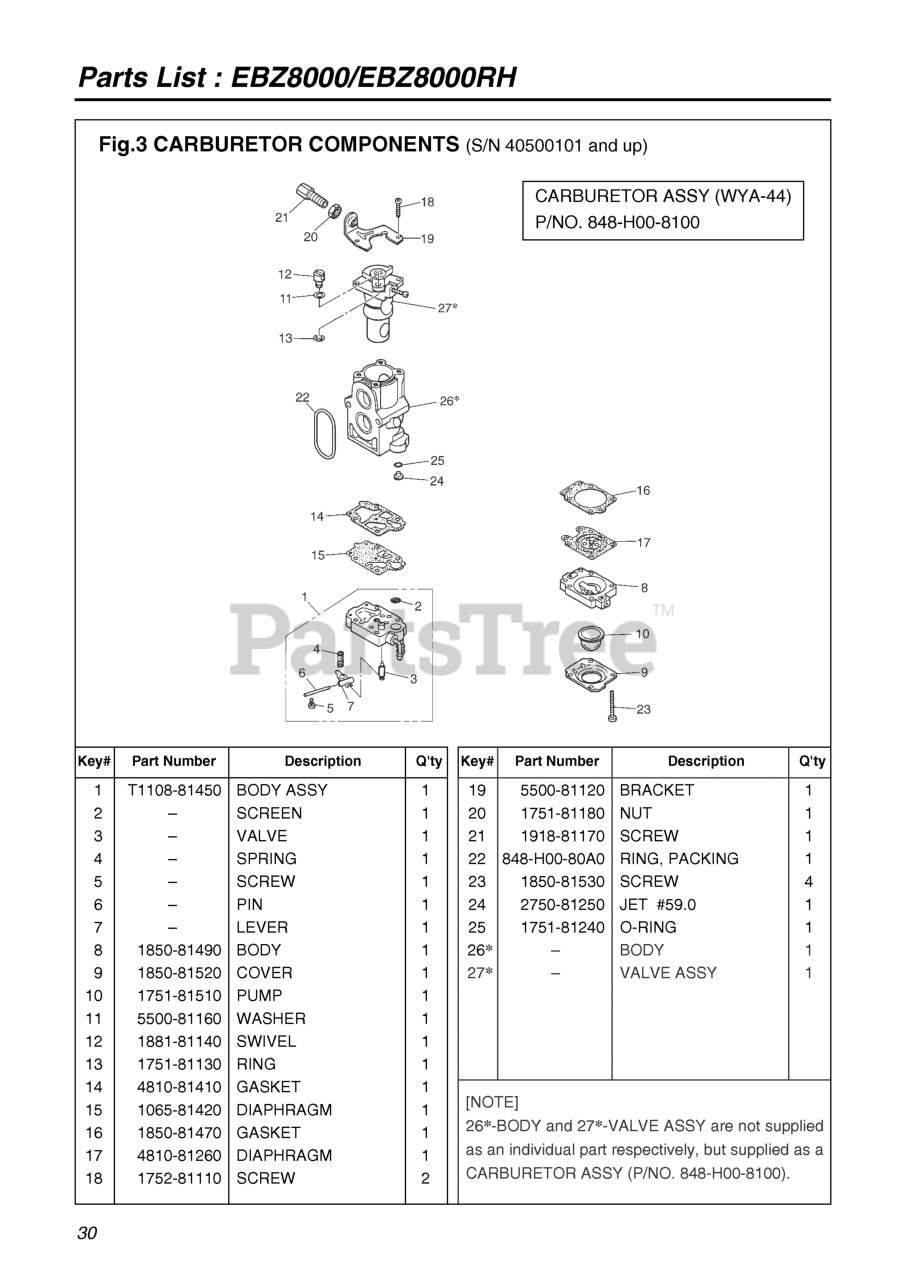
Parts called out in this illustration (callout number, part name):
1	BODY ASSY.
2	SCREEN
3	VALVE
4	SPRING
5	SCREW
6	PIN
7	LEVER
8	BODY, PURGE
9	COVER, PUMP
10	PUMP, PRIMING
11	WASHER
12	SWIVEL
13	RING
14	GASKET, PUMP
15	DIAPHRAGM
16	GASKET, DIAPHRAGM
17	DIAPHRAGM (RPLS 3310-81260)
18	SCREW
20	NUT, CABLE ADJUSTER
21	SCREW, CABLE ADJUSTER
22	RING, PACKING
23	SCREW
24	JET
25	RING, O
26	CARBURETOR-A (WYA-44)
27	CARBURETOR-A (WYA-44)
NI	CARBURETOR-A (WYA-44)
